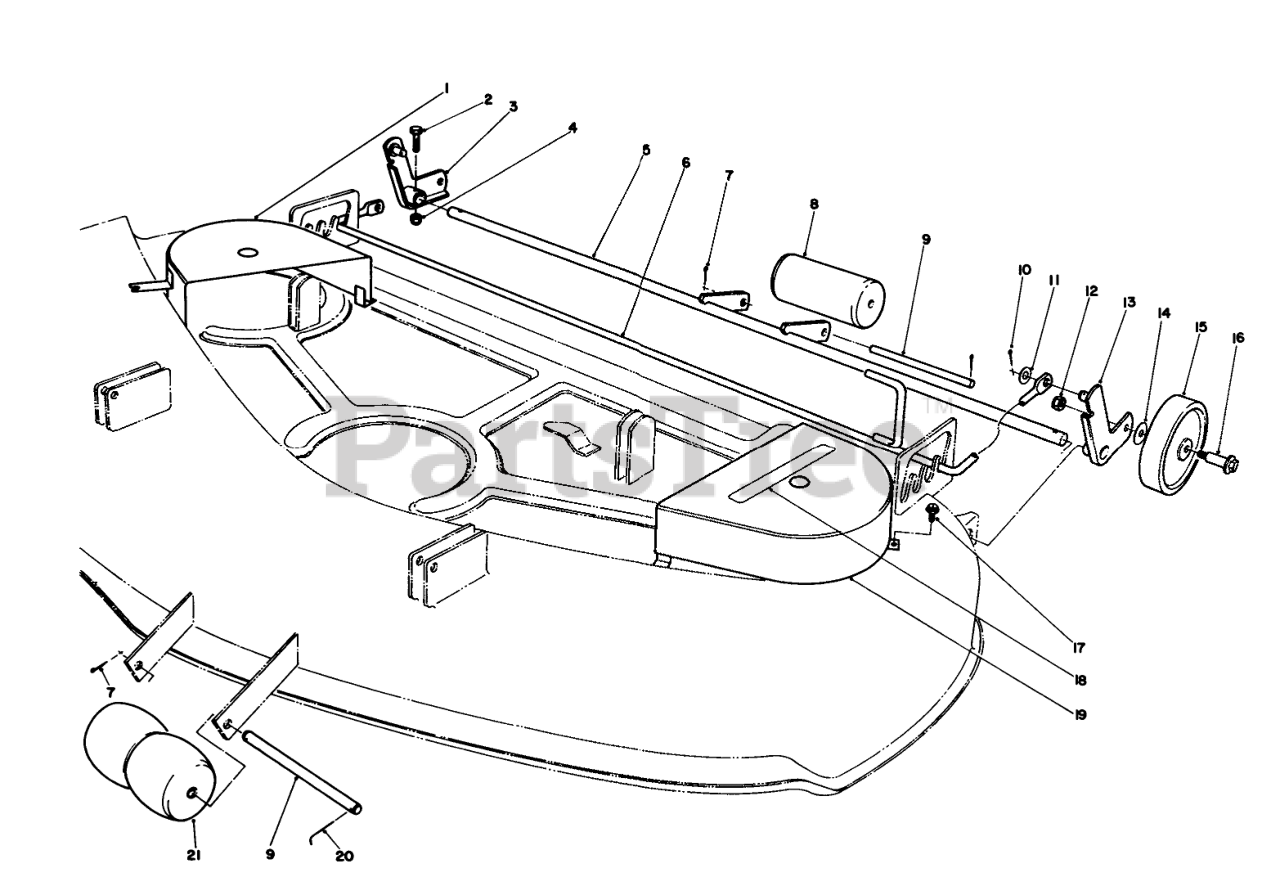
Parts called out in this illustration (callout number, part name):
1	Cover-Spindle R.H.
2	SCREW-HH
3	RH WHEEL BRKT WA B
4	NUT-LOCK, NI
6	Bracket
7	PIN-COTTER
8	ROLLER-DECK
9	ROLLER SHAFT
10	PIN-COTTER
11	WASHER-FLAT
12	NUT-LOCK, NI
13	LH WHEEL BRKT WA B
14	WASHER-THRUST
15	DECK WHEEL
16	BOLT-WHEEL
17	SCREW-HWHTF
18	DECAL-NO STEP
19	Cover-Spindle
20	PIN-SPECIAL
21	ROLLER
